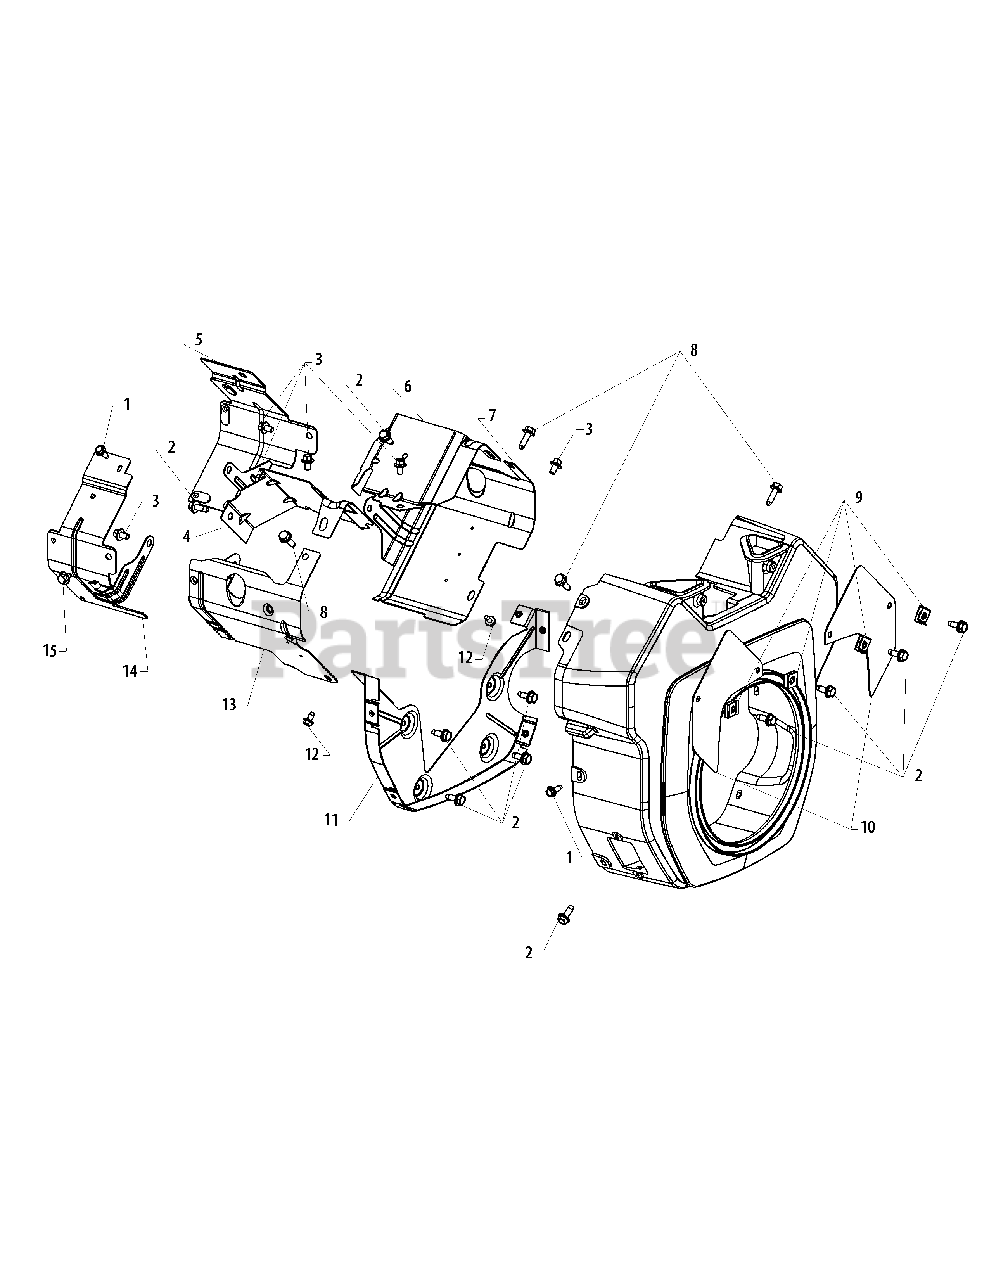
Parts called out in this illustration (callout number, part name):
1	Screw, Flg Thd Frm M5x0.8x16
2	Screw, Flg Thd Frm M6x1.0x16
3	Screw, Flg M6x1.0x10
4	Baffle, Valley #2 Cylinder
5	Baffle, Ducted Air-Starter
6	Baffle, Valley #1 Cylinder
7	Kit, Cyl Barrel - #1 Side
8	Screw, Flg Thd Frm M6x1.0x20
9	Clip, Baffle Mounting
10	Kit, Access Panel
11	Kit, Backing Plate
12	Screw, Flg Thd Frm M5x0.8x10
13	Kit, Cyl Baffle - #2 Side
14	Baffle, Ducted Air-Oil Filter
15	Screw, Flg Thd Frm M6x1.0x10
